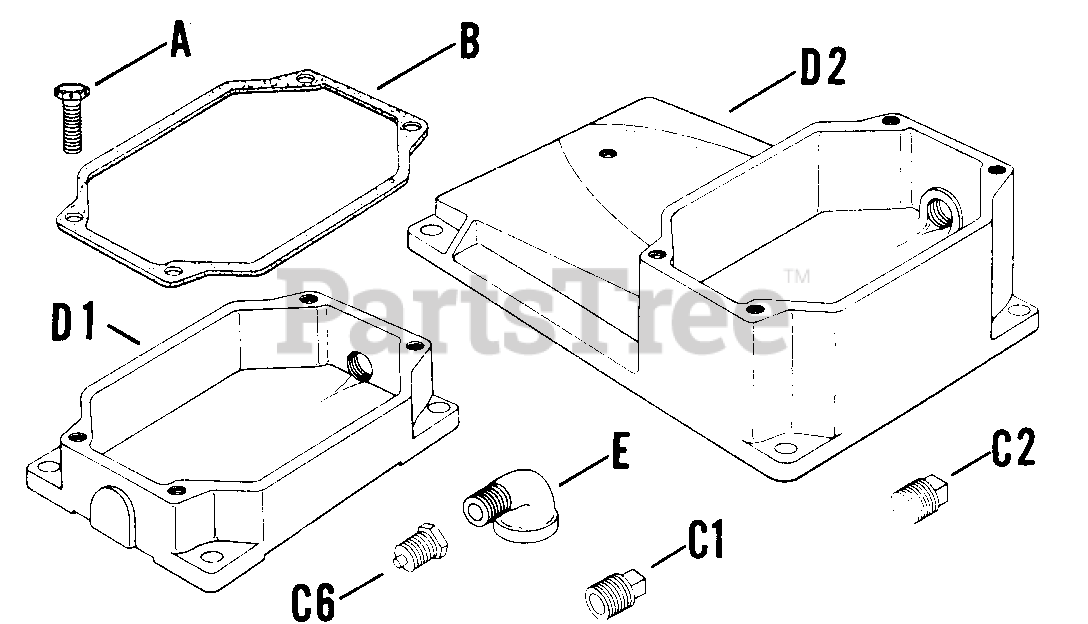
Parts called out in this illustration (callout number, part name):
B	GASKET - USE 41 041 03
C1	PLUG,PIPE 1/2 NPTF SQUARE HD USE 25 139 61-S
D1	PAN - USE 41 199 07
